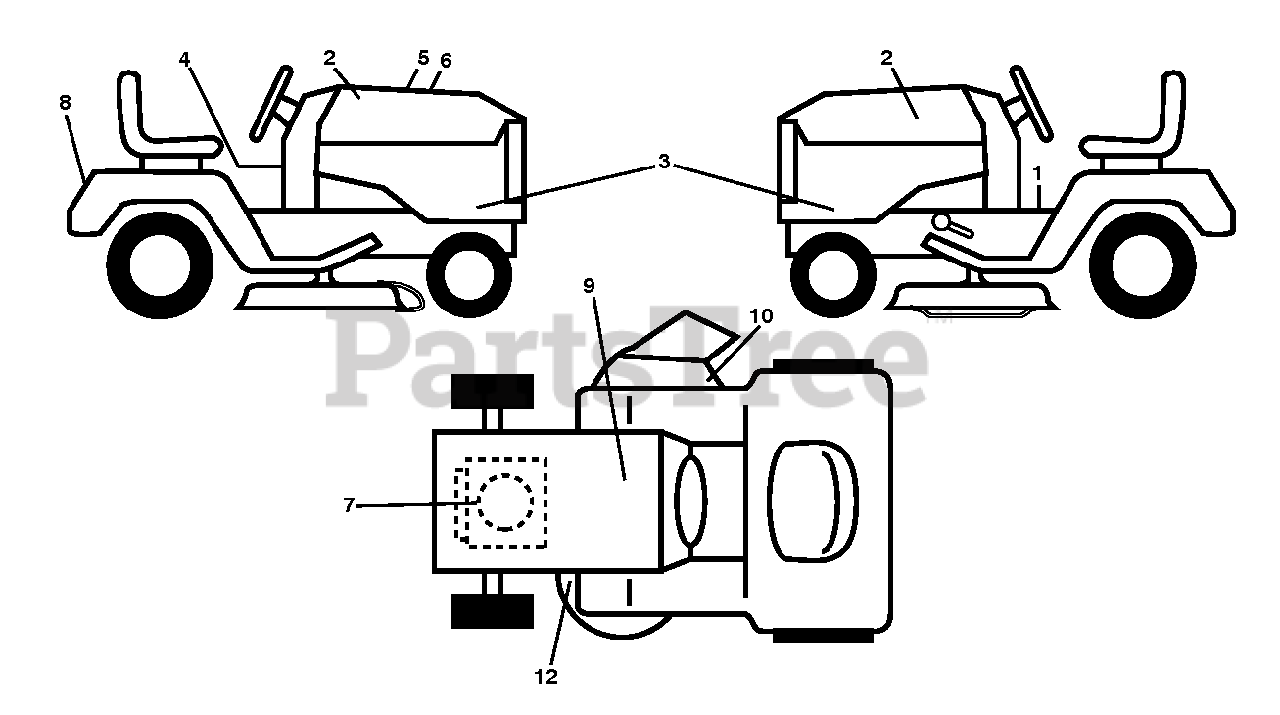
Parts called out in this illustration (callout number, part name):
1	DECAL.WARN.STARTINST.LOWEARIEN
2	DECAL.BADGE.170MM.TEXTLOGO.
3	DECAL.SIDE.PANEL.YTH22V46.2013
4	DECAL, WARNING SPARK ARRESTOR
5	DECAL.WARNING.CUST.RESP.E85.
6	DECAL.RPL.BSM44.INTK.TLW.46.K4
7	DECAL.ENG.BS.22HP.INTK
8	DECAL.FENDER
9	DECAL BTRY SYMBOLS
10	DECAL.MOWER.WARN.KEEP.HAND.AWY
12	DECAL.V-BELT.SCH.42/46"MEC/ELE
